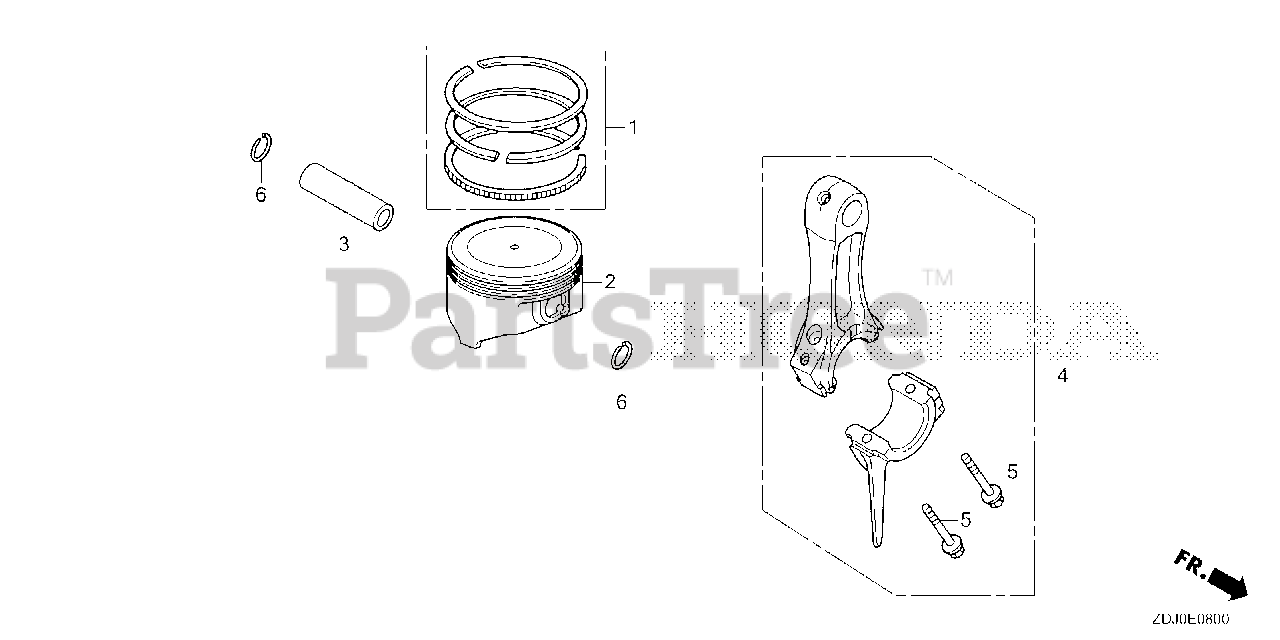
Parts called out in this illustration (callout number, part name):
1	RING SET, PISTON (STD) (NIPPON)
3	PIN, PISTON
4	ROD ASSY., CONNECTING
4	ROD ASSY., CONNECTING (UNDER SIZE)
5	BOLT, CONNECTING ROD (6X32)
6	CLIP, PISTON PIN (13MM)
